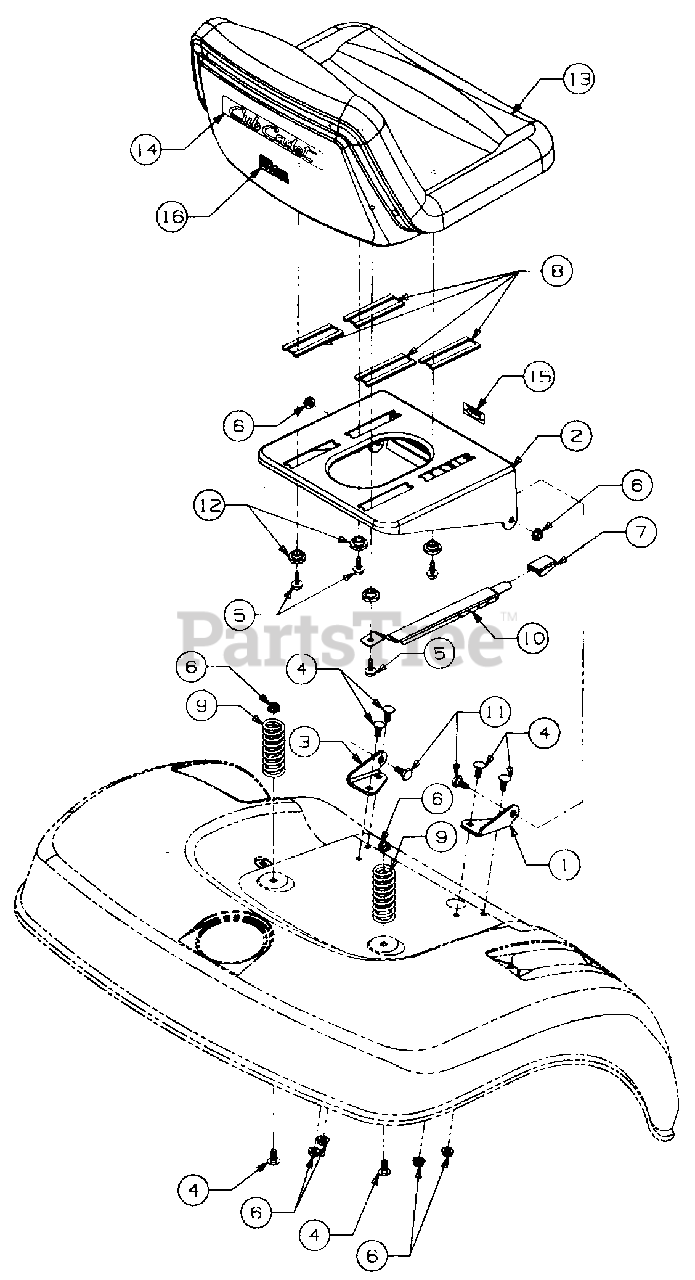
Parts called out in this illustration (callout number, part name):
1	Bracket, RH Seat Pivot
2	Seat, Base
3	Bracket, LH Seat Pivot
4	Bolt, Carriage, 5/16-18 x .75
5	Screw, Hex Wash Hd Tap 5/16-18 x .75
6	Nut, Hex Flange Lock, 5/16-18
7	Knob, Seat Adjuster
8	Slide, Seat
9	Spring, Compression 1.9 OD x 2.4 Lg
10	Adjuster, Seat
11	Bolt, Shoulder
12	Spacer, Shoulder
13	Seat, Medium Back
14	Graphic, Seat Back Script
15	Graphic, Seat Adjuster
16	Graphic, Made in USA
